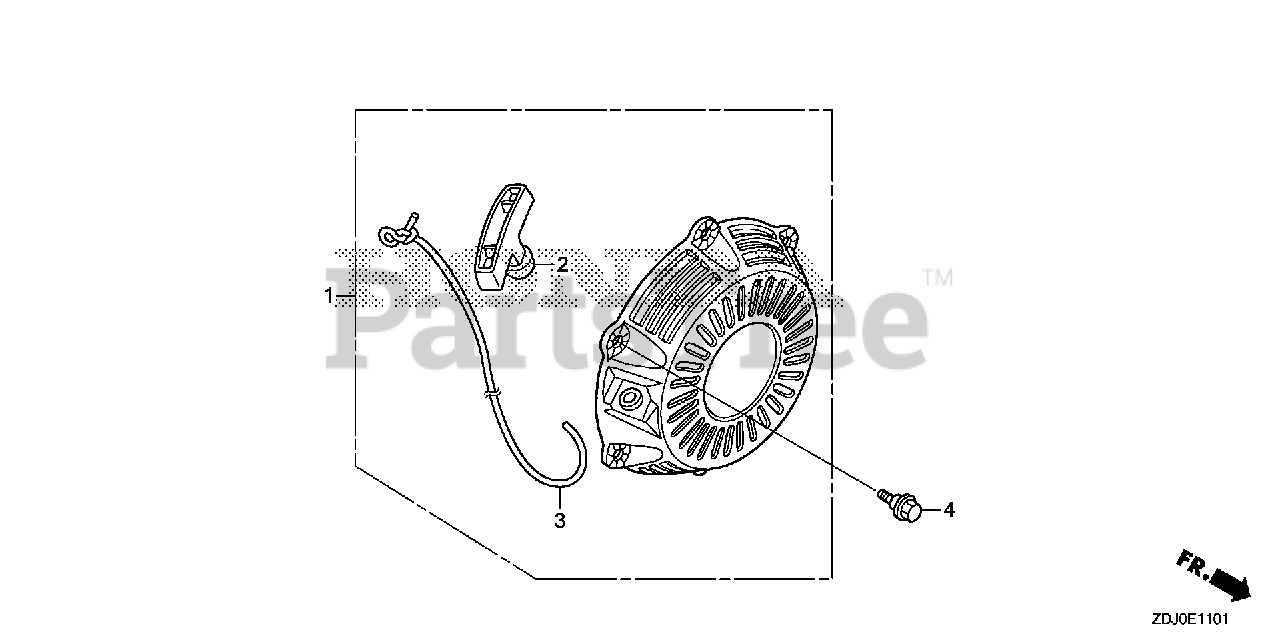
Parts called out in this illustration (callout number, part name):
1	STARTER ASSY., RECOIL *R280* (POWER RED)
2	GRIP, STARTER
3	ROPE, STARTER
4	BOLT, FLANGE (6MM)
